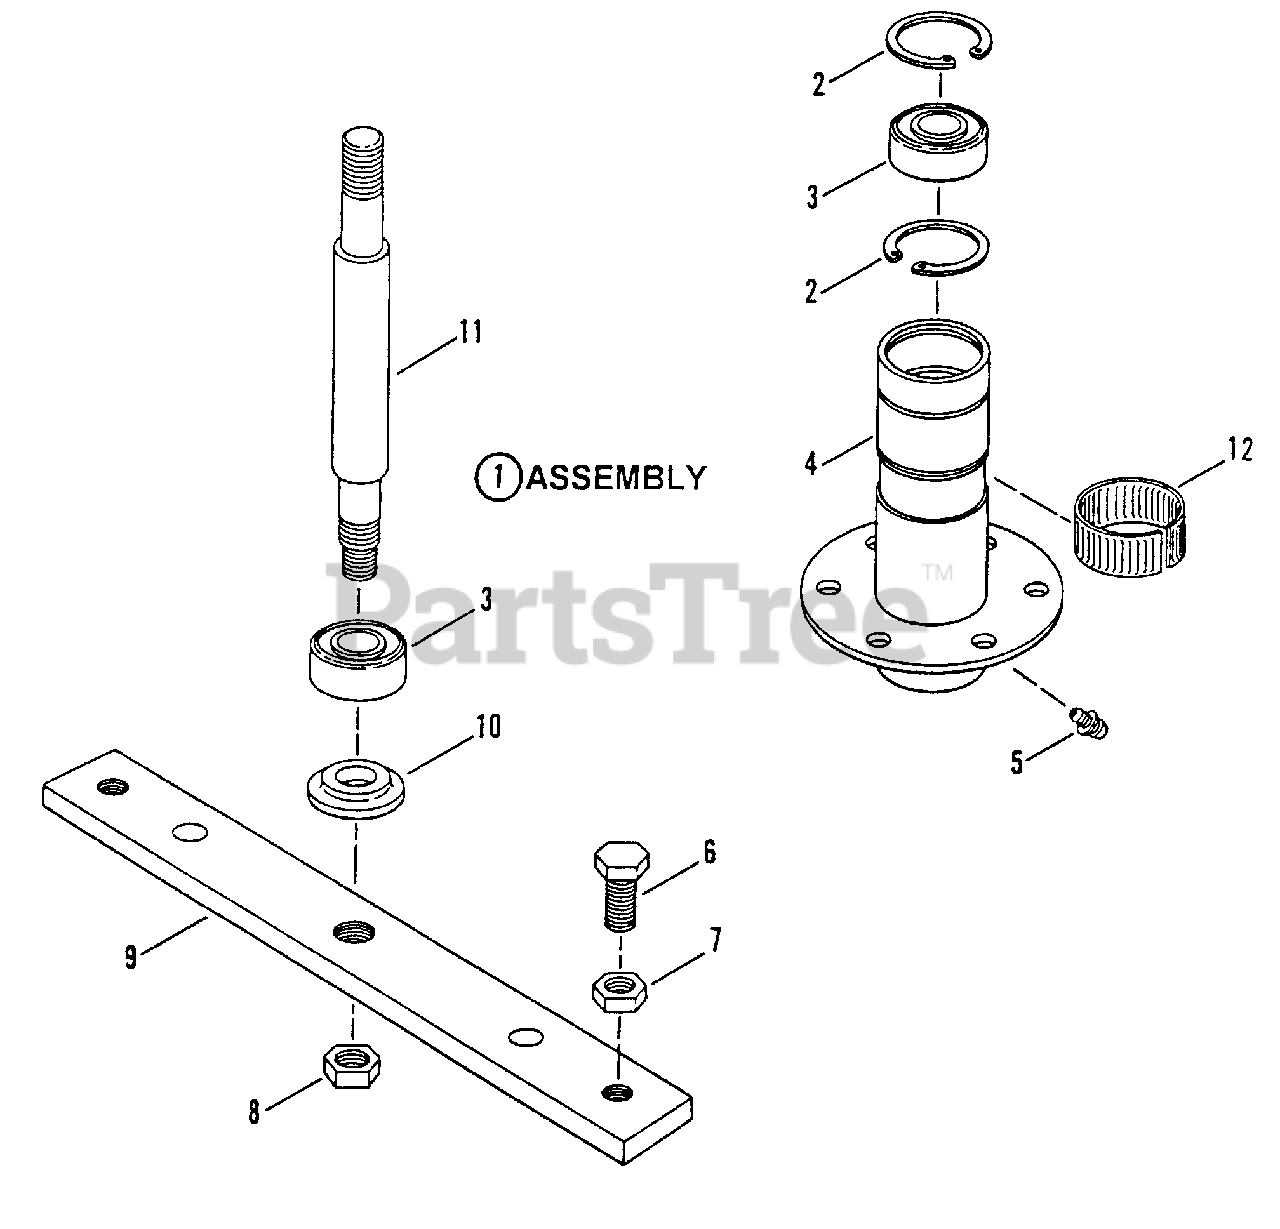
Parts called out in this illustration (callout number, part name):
1	ASSEMBLY, Spindle Housing, 30" Cutting Deck
2	RING, Retaining
3	BEARING, Spindle
4	HOUSING, Spindle
5	FITTING, Lube (Press fit for .187 hole-no ball)
6	SCREW, 1/2-20 x 1-1/4" Hex Head Cap, Grade 5
7	NUT, 1/2-20 Hex Jam
8	NUT, 5/8-18 Hex Center Lock Jam
9	HOLDER, Blade
10	WASHER, Spindle
11	SPINDLE, 7.54" Long
12	RING, Tolerance
